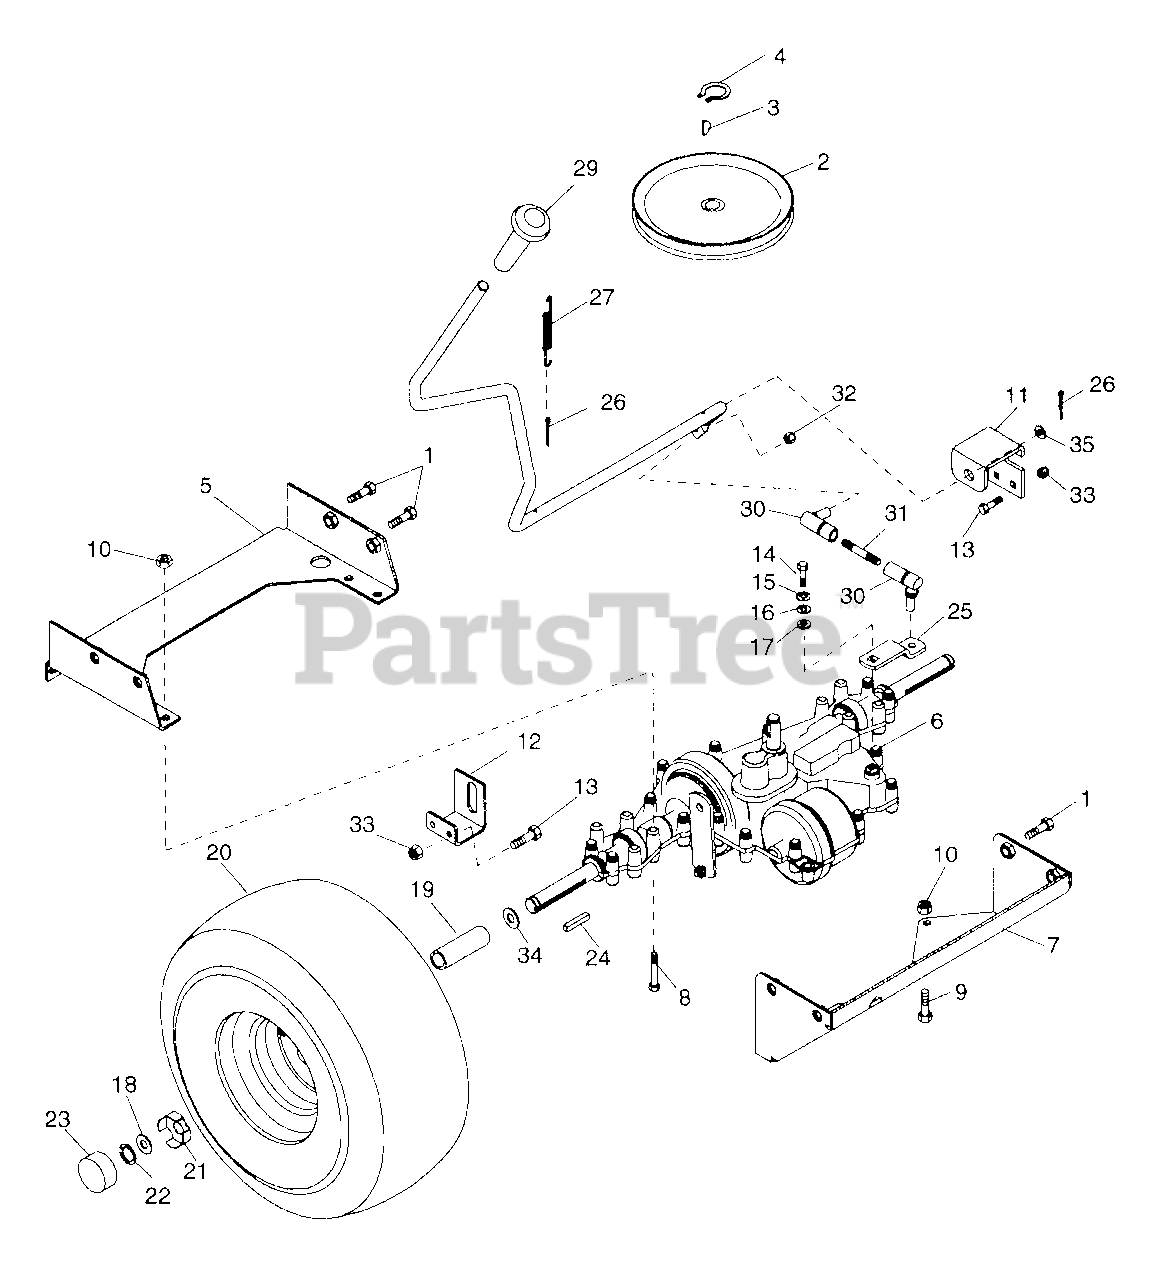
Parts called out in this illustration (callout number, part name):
1	SCR-TAP .375-16X.75 HWH PL TR
2	PLY-TRANS 7.00X.626
3	KEY-WDRF .188X.75X.313 SAE 9
4	RG-RTNG-EXT .625X.035
5	REAR TRANSAXLE MOUNT
6	TRANSAXLE-GEAR 940-011 5-SPD
7	TORQUE MOUNT
8	BLT-HEX .31-18X2.50 PL GR5
9	BLT-HEX .31-18X2.00 PL GR5
10	NUT-LK-TOP .312-18 GR C PL
11	SHIFT PIVOT BRACKET
12	SHIFT GUIDE BRACKET
13	BLT-HEX .25-20X.75 PL GR2
14	BLT-HEX .25-28X.75 PL GR5
15	WSHR-LK .250X.077 HVY PL
16	WSHR-FL-STL .328X1.0X.094 PL
17	WSHR-FL-STL .505X1.000X.062
18	WSHR-FL-STL .755X1.375X.062 PL
19	BSHG-SLV .750X1.125X1.062
20	T/WHL ASSY 20X8.00-8
21	SPINDLE CUP
22	RG-RTNG-EXT .750X.050
23	HUB CAP
24	KEY-SQ .188X2.0X.188 SAE 8630
25	SHIFT ARM
26	PIN-COTR .12X1.0 PL
27	SG-TENS .063X.44X1.56
28	SHIFT LEVER
30	SNAP IN BALL JOINT
31	SHIFT LINK
32	NUT-LK-CTR .312-24 PL
33	NUT-LK-NYL .250-20 PL
34	WSHR-FL-STL .754X1.000X.032
35	WSHR-FL-STL .520X.827X.062 YZ
